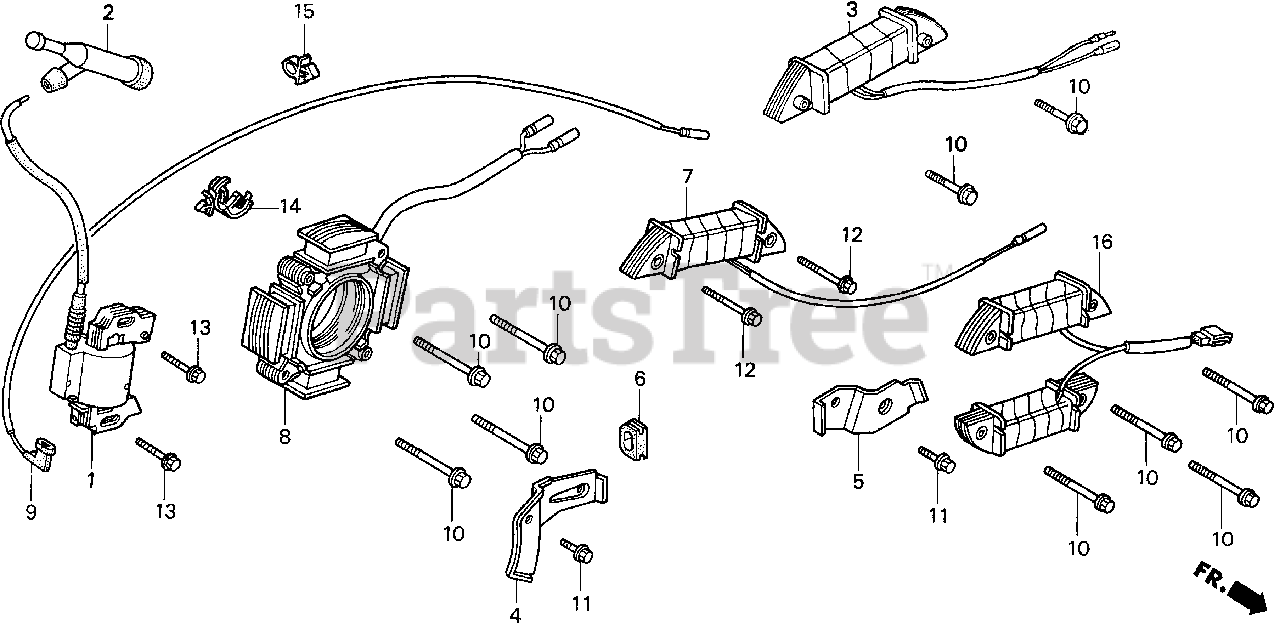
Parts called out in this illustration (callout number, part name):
1	COIL ASSY., IGNITION
2	CAP ASSY., NOISE SUPPRESSOR
3	COIL ASSY., LAMP (12V/25W)
5	CLAMP, WIRE
6	GROMMET, WIRE
9	WIRE, STOP SWITCH (430MM)
10	BOLT, FLANGE (6X40)
11	BOLT, FLANGE (6X12) (CT200)
13	BOLT, FLANGE (6X28)
14	CLIP, WIRE HARNESS
